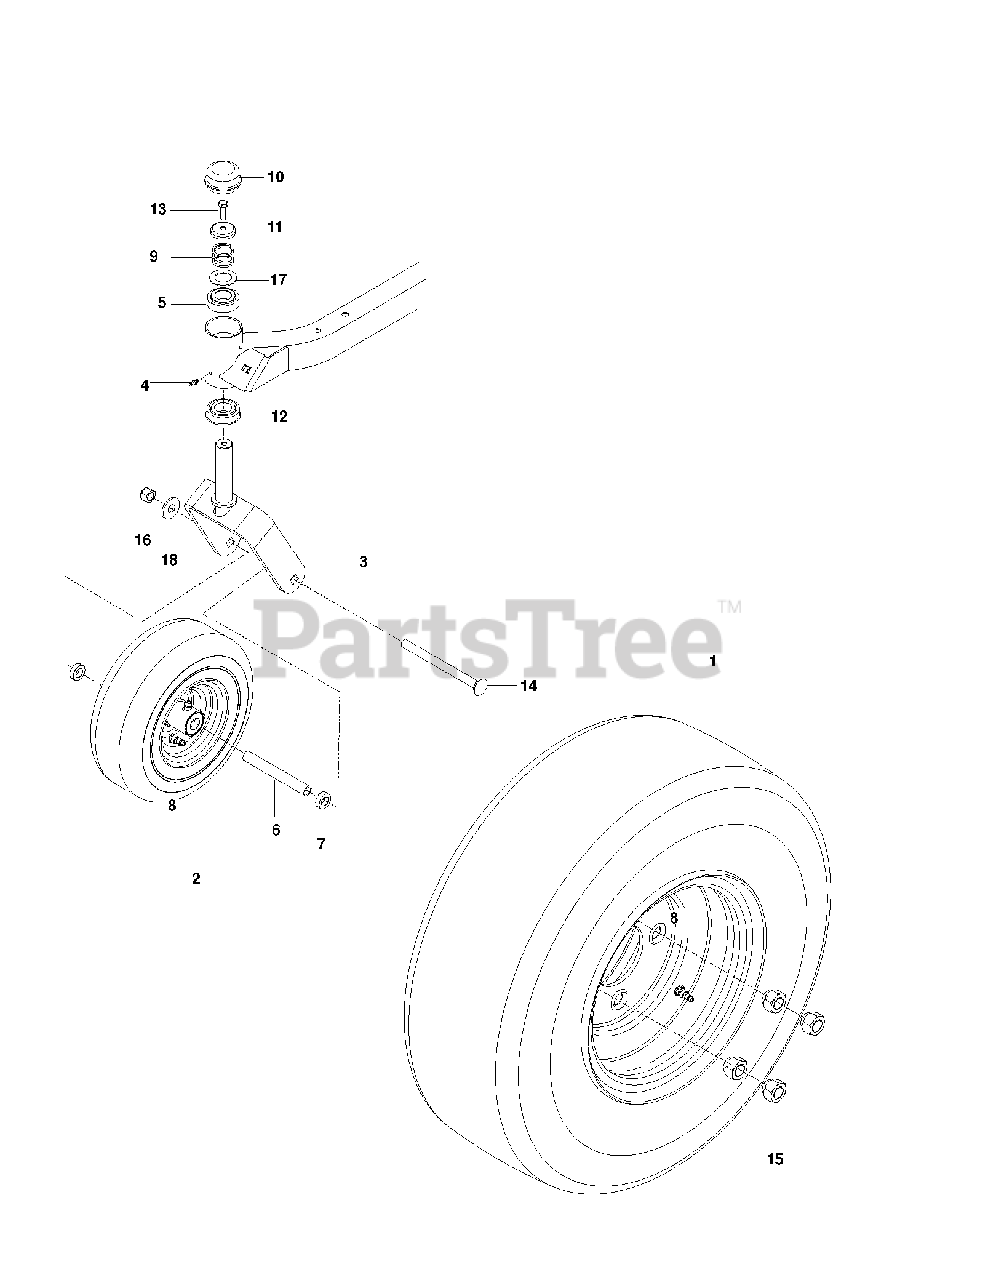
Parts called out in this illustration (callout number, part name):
3	CASTER DK BLUE
4	ZERK, 3/16, DRIVE IN
5	BUSHING, CASTER
7	SPACER, 5/16"
8	VALVE STEM TR-412
9	SPRING, CASTER
10	GREASE CAP
11	CASTER.PLUG
12	BEARING FLANGED
13	5/16-18X1 HHB G5W/NY
14	RHSNB 1/2-13 X 6.50 GR2 ZD
15	LUG NUT 1/2F
16	NUT 1/2-13 HEX CNTRLK GR 5 ZD
17	WASHER, 1.025 ID X 1.64
18	WASH USS FLAT 1/2
